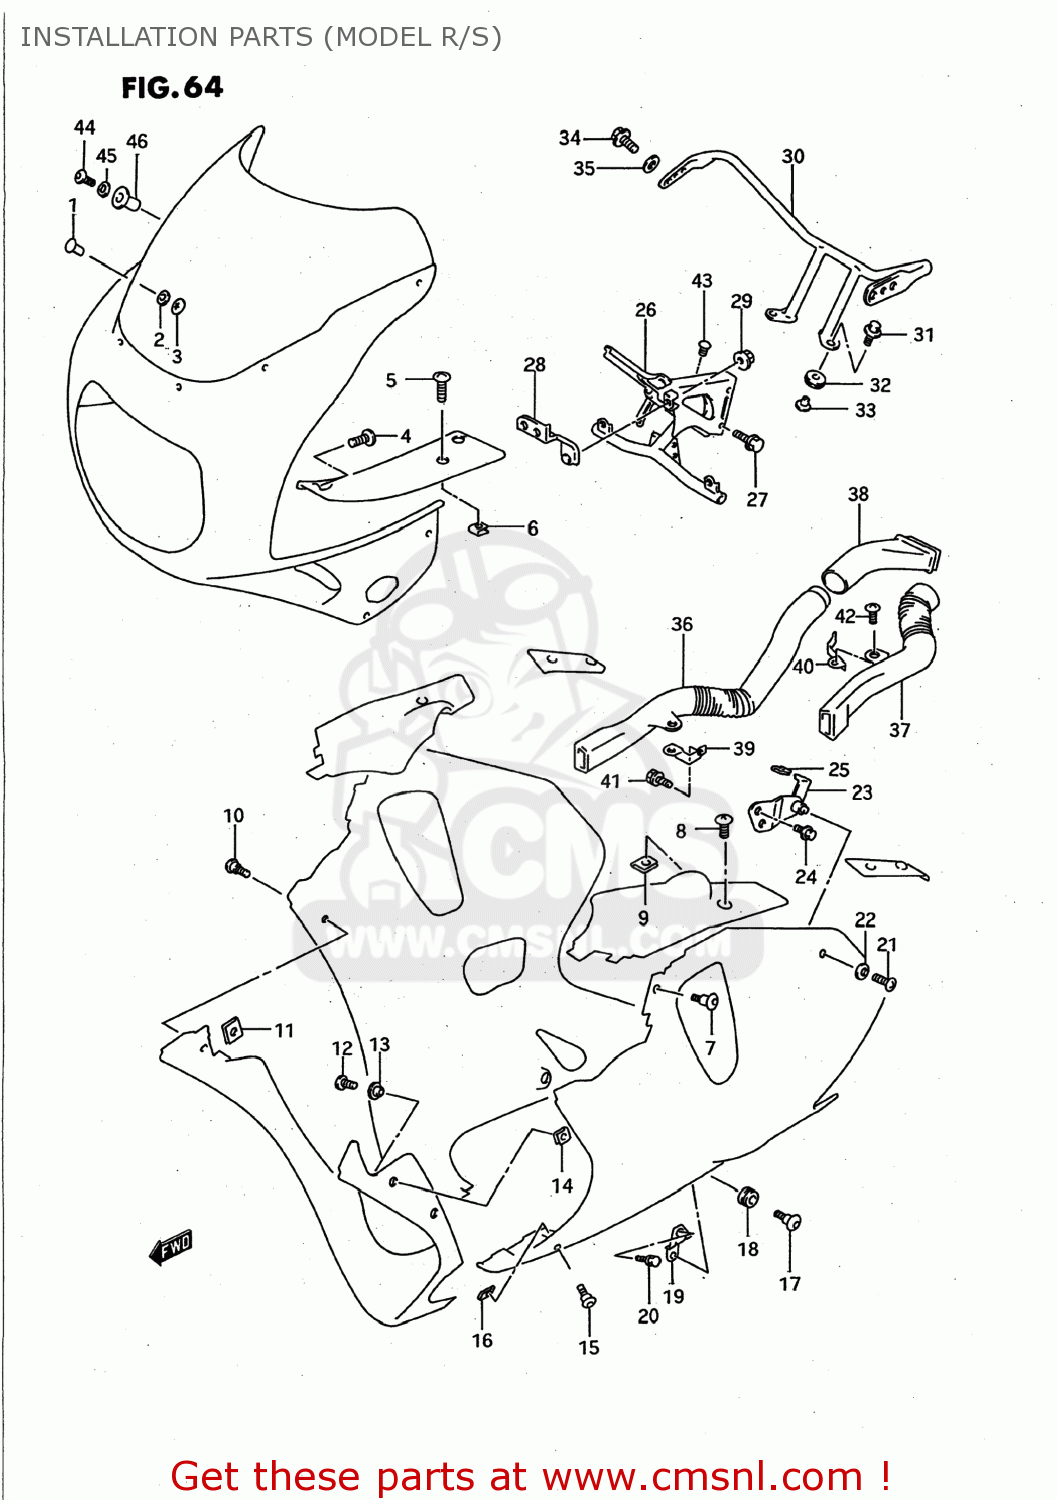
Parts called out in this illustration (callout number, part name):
1	PIN,WINDSCREEN
2	CUSHION
3	NUT
4	SCREW 5X10
5	SCREW L:12
6	NUT
7	SCREW(5X16)
8	SCREW L:12
9	NUT
10	SCREW(5X16)
11	NUT,RH & CTR UNDER COWLING
12	SCREW
13	WASHER(5.2X14X1.5)
14	NUT
15	SCREW(5X16)
16	NUT,RH & CTR UNDER COWLING
17	SCREW(6X20)
18	CUSHION
19	BRACKET,UNDER COWLING LWR,R
20	BOLT
21	SCREW(6X10)
22	WASHER
23	BRACKET,UNDER COWLING,UPPER
24	BOLT
25	NUT
26	BRACE,COWLING
27	BOLT
28	BRACKET,HEADLAMP
29	NUT
30	BRACE,RR VIEW MIRRORR
31	BOLT(6X25)
32	CUSHION
33	WASHER
34	SCREW(6X12)
35	WASHER(6.2X19X1.5)
36	PIPE,AIR INTAKE FR,R
37	PIPE,AIR INTAKE FR,L
38	PIPE,AIR INTAKE,REAR,RIGHT
39	BRACKET,AIR INTAKE,RIGHT
40	BRACKET,AIR INTAKE,LEFT
41	BOLT
42	SCREW 6X12
43	CAP(OD:14)
44	SCREW(5X14)
45	WASHER
46	NUT
